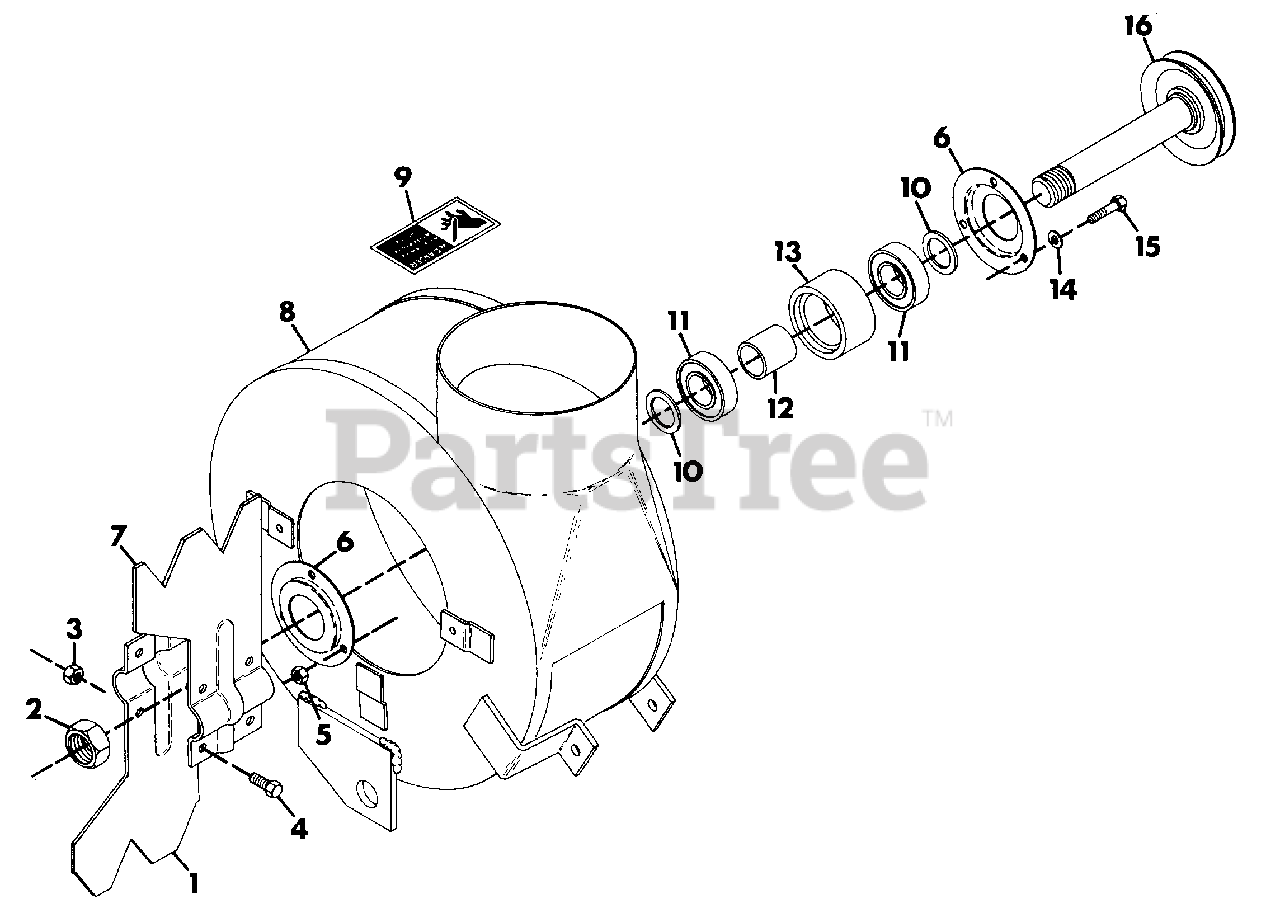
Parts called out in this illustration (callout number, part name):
1	BLADE, FAN
2	NUT, HEX 1-14 JAM LOCK
3	NUT, LOCK 5/16-18
4	BOLT, HEX 5/16-18X.625
5	NUT, LOCK 1/4-20
6	BEARING, FLANGE
7	BLADE, FAN
8	HOUSING, FAN
9	DECAL, DANGER HAND
10	WASHER, 1.000/1.031X1.500X.125
11	BEARING, BALL
12	SPACER
13	HOUSING
14	WASHER, .263/.273X.562X.046
15	BOLT, HEX 1/4-20X2.00
16	WELDMENT, SPINDLE
